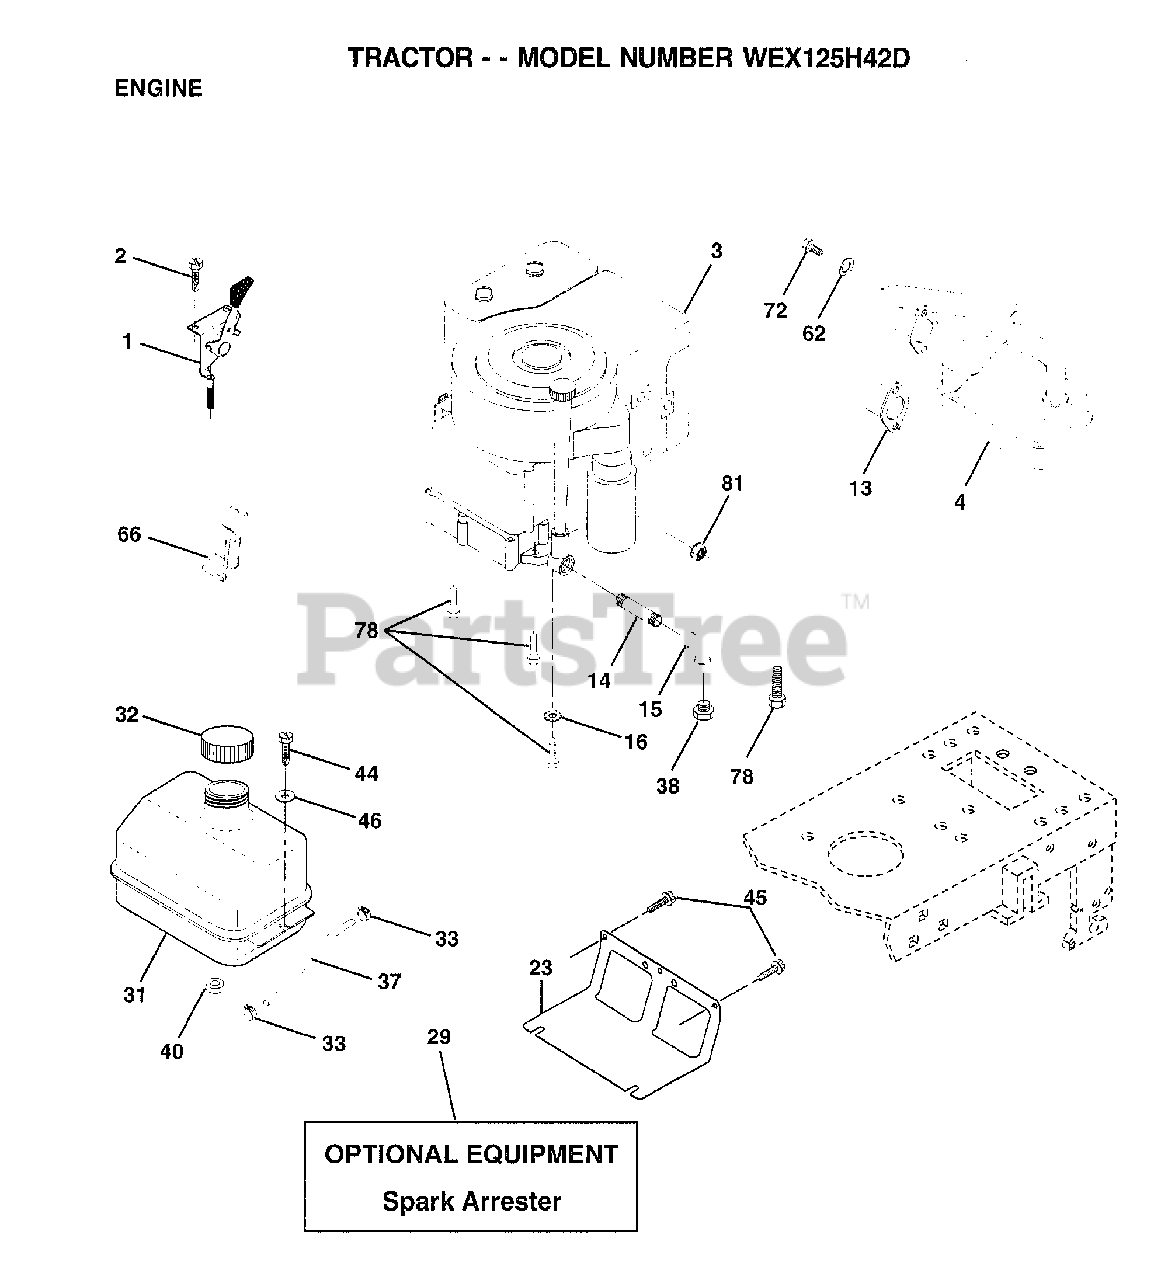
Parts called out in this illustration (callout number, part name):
1	CONTROL.THTL.23.5
2	SCREW LT
4	MUFFLER
14	PIPE NIPPLE
15	ELBOW
16	LOCKWASHER
23	SHIELD BROWNING
31	TANK.FUEL.LT.
32	CAP ASM FUEL
33	HOSE CLAMP
37	LINE FUEL
44	SCREW
45	SCREW
46	WASHER
62	LOCKWASHER
66	"STOP,DASH THROTT"
72	SCREW
78	SCREW
81	NUT
